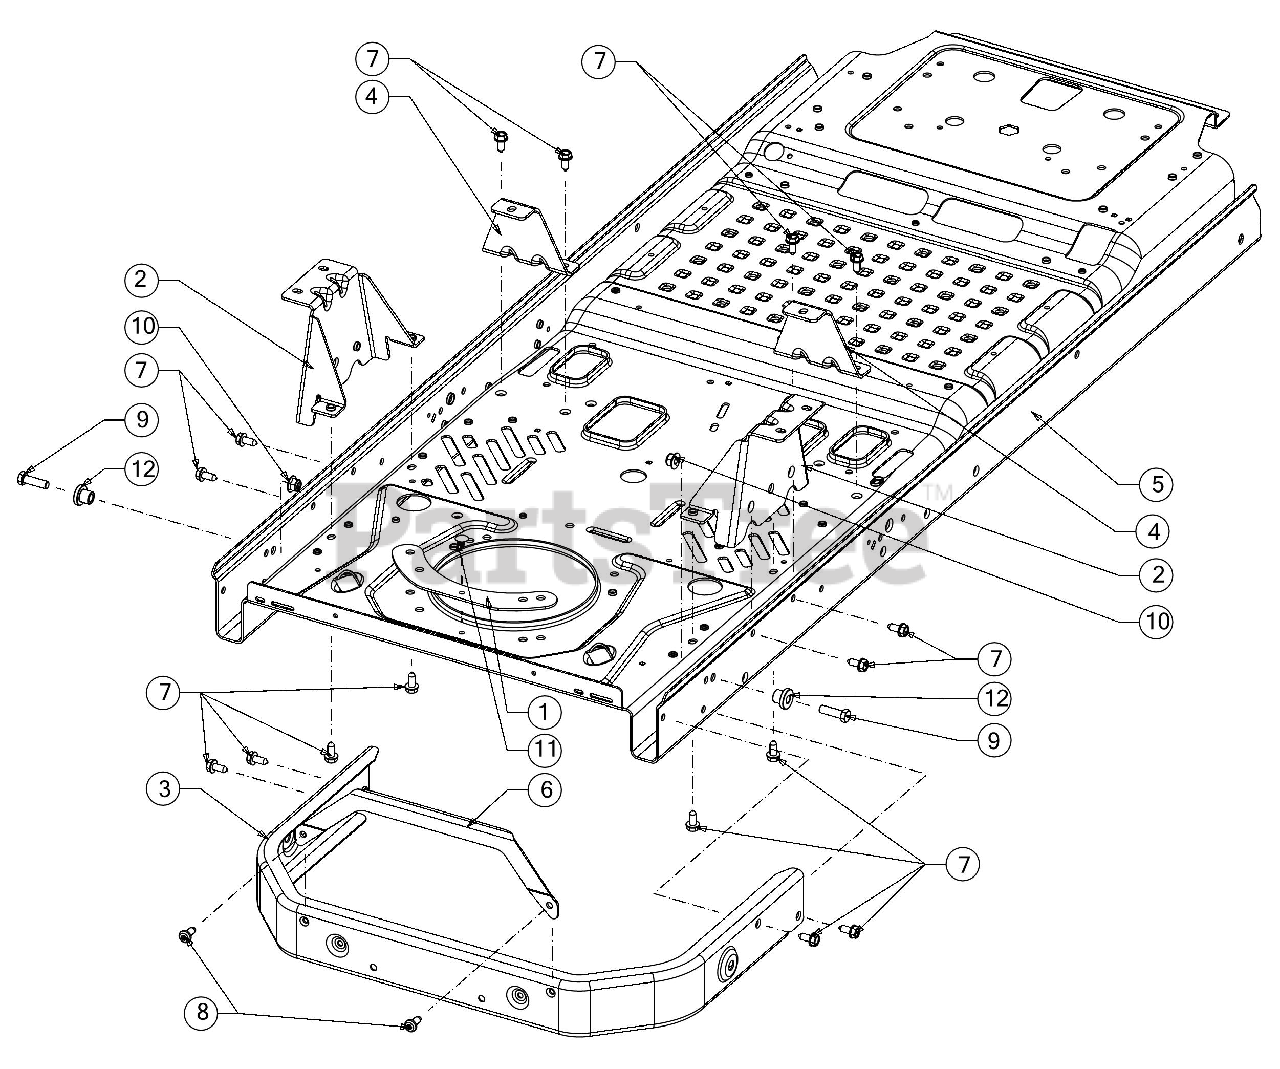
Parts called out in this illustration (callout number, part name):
1	RETAINER PLATE
2	TRANSMISSION MOUNTING BRACKET
4	TRANSMISSION MOUNTING BRACKET
7	SCREW 5/16-18 X .750
8	SCREW 5/16-18 X.75
9	SCREW 3/8-16 X 1.25 GR5
11	RATCHET CLIP
12	SHOULDER SPACER
